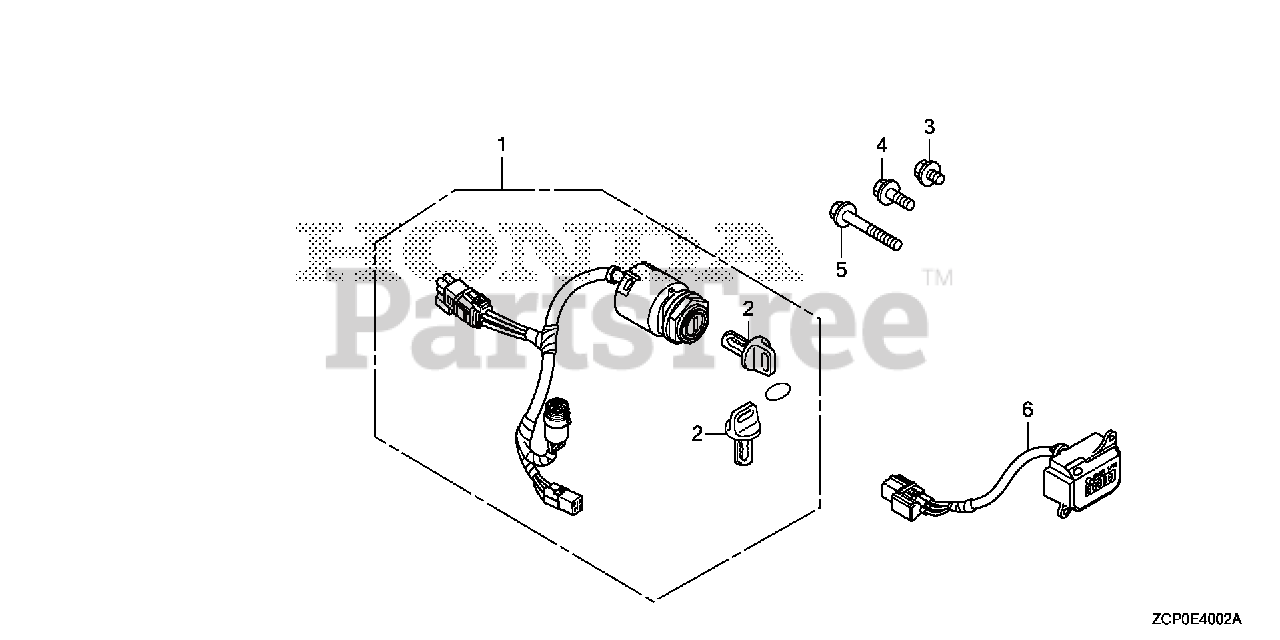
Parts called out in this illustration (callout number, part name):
1	SWITCH ASSY., COMBINATION
2	KEY ASSY., COMBINATION SWITCH (W05)
3	BOLT, FLANGE (6X8)
4	BOLT, FLANGE (6X14)
5	BOLT, FLANGE (6X30)
6	METER ASSY., HOUR
